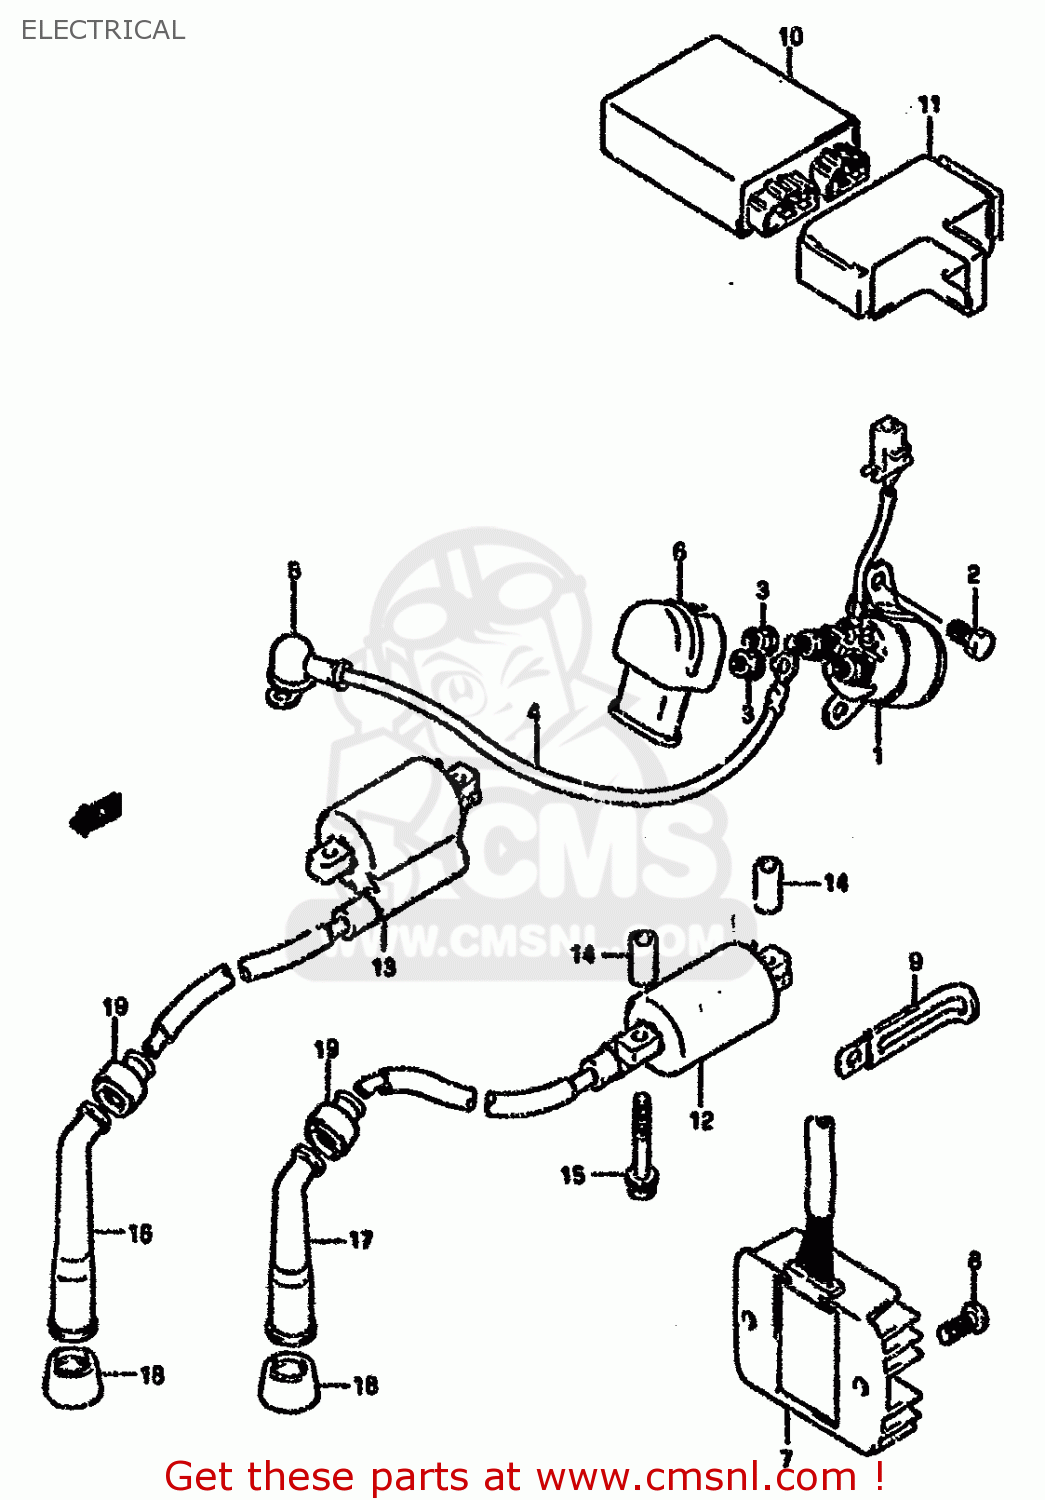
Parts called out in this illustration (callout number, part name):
1	RELAY ASSY,STARTING MOTOR
2	BOLT
3	NUT
4	WIRE,STARTER MOTOR LEAD
5	CAP,STARTER MOTOR LEAD
6	CAP,STARTER RELAY TERMINAL
7	RECTIFIER ASSY
8	SCREW
9	CLAMP
10	IGNITOR ASSY
11	CUSHION,IGNITER
12	COIL ASSEMBLY,IGNITION
13	COIL ASSEMBLY,IGNITION
14	SPACER(6.4X10X19)
15	BOLT
16	CAP,SPARK PLUG
17	CAP ASSY,SPARK PLUG
18	SEAL,SPARK PLUG CAP
19	SEAL,HIGH TENSION CORD
